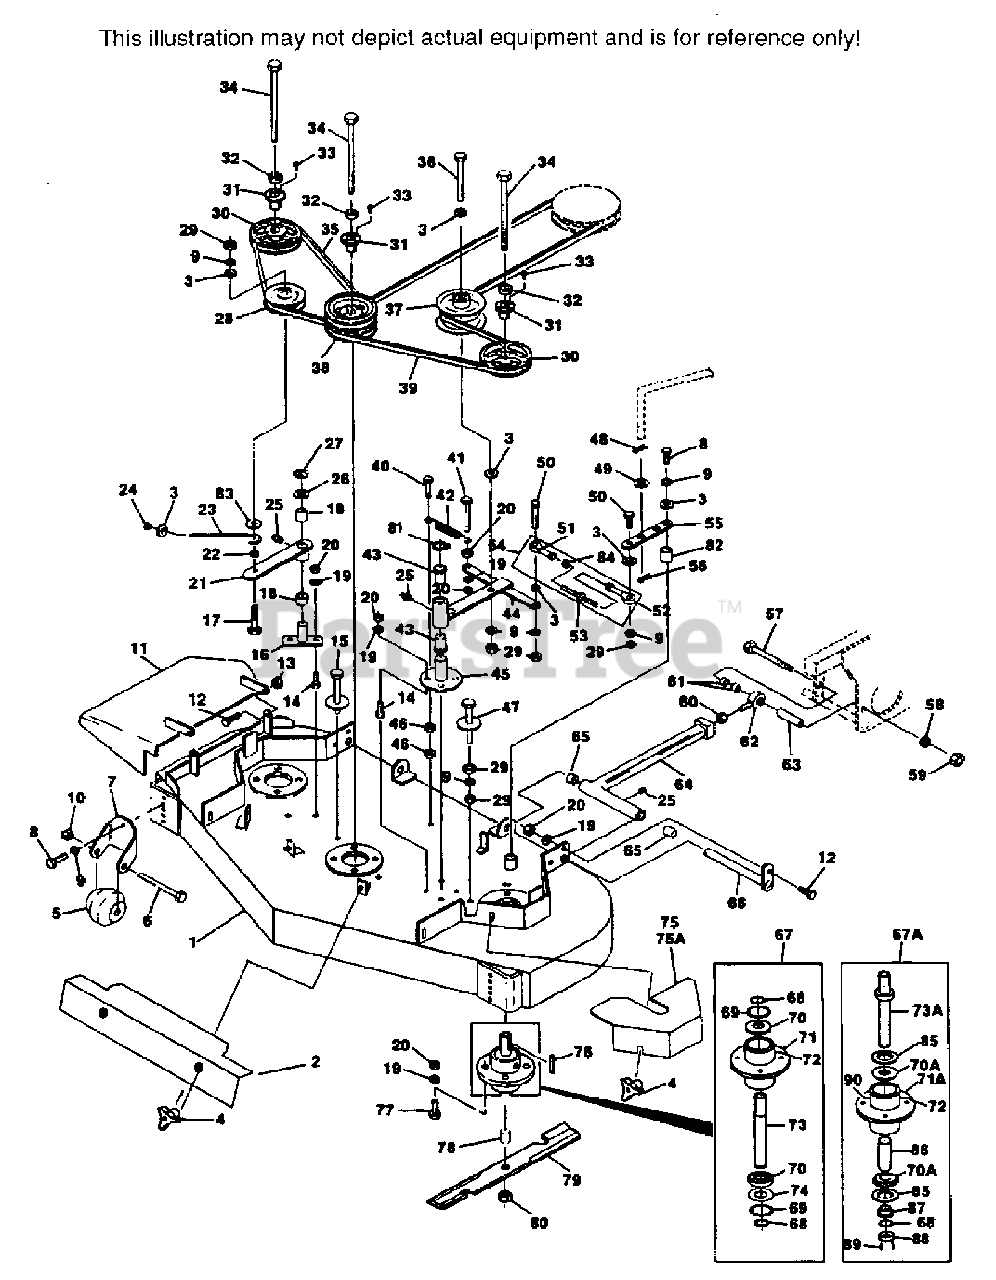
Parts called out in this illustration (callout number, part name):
1	CUTTER DECK(INCLUDES DECALS)
2	BELT COVER - FRONT
4	WING NUT, 3/8-16
5	ANTI-SCALP WHEEL
7	ANTI-SCALP WHEEL BRACKET
10	HEX NUT, 5/8-11 ELASTIC STOP
11	DISCHARGE CHUTE
13	HEX NUT, 5/16-18 ELASTIC STOP
15	BELT GUIDE
16	IDLER PIVOT BASE
18	BUSHING
21	IDLER ARM(INCLUDES BUSHINGS & GREASE FTG.)
22	SPACER
23	"J" ROD
24	HEX NUT, 3/8-16 ELASTIC STOP
25	GREASE FITTING
26	FLAT WASHER, 3/4 SPECIAL
27	RETAINING RING, 3/4 EXTERNAL "E"
28	PULLEY, IDLER
30	PULLEY(INCLUDES ITEMS 31 & 33)
31	TAPERED HUB
32	SPACER
34	HEX HEAD BOLT, 5/8-11 X 9-1/2
35	BELT, RH BLADE DRIVE
37	PULLEY, IDLER - CUTTER ENGAGEMENT
38	PULLEY, DOUBLE
39	BELT, BLADE DRIVE
42	SPRING, IDLER TENSION
43	BUSHING
44	IDLER ARM(INCLUDES BUSHINGS & GREASE FTG.)
45	IDLER PIVOT BASE
47	BELT GUIDE
51	BALL JOINT - RH(SILVER)
52	BALL JOINT - LH(GOLD)
53	LINK, TURNBUCKLE
54	TURNBUCKLE ASSEMBLY
55	DECLUTCH LINK, CUTTER ENGAGEMENT
56	HAIR PIN, 1/8" DIA.
61	SPACER
62	BALL JOINT
63	SPACER
64	PUSH ARM(INCLUDES BUSHINGS & FITTING)
65	BUSHING
66	PUSH ARM SHAFT
67	CUTTER SPINDLE ASSEMBLY(INCLUDES 68-74)
67A	CUTTER SPINDLE ASSEMBLY COMPLETE, TAPER
68	RETAINING RING, 1" EXTERNAL INVERTED
69	RETAINING RING, 2-7/16" INTERNAL BASIC
70	BEARING, CUTTER SPINDLE
70A	BEARING & CUP, TAPERED SPINDLE
71	SPINDLE HOUSING
71A	SPINDLE HOUSING, TAPERED SPINDLE
72	GREASE FITTING
73	SPINDLE SHAFT
73A	SPINDLE SHAFT, TAPERED SPINDLE
74	WASHER, 1-5/16 X 2-7/16 X 16 GA.
75	BELT COVER - RH
75A	BELT COVER - LH
76	KEY, 1/4 X 1/4 X 2
78	SPACER - USE WITH BALL BEARING SPINDLE
78	SPACER-USE WITH TAPER BEARING SPINDLE
79	CUTTER BLADE
81	RETAINING RING 1 1/8" EXT. E
82	SLEEVE, CAM CLUTCH
83	3/8" FLAT WASHER, 3/8 X 1 1/2 X .06
84	HEX NUT 3/8-24 UNF
85	SEAL, CUTTER SPINDLE, TAPERED
86	SPACER, TAPERED SPINDLE
87	BUSHING, TAPERED SPINDLE
88	1/4" BLADE SPACER, TAPERED SPINDLE
90	RELIEF FITTING, TAPERED SPINDLE
